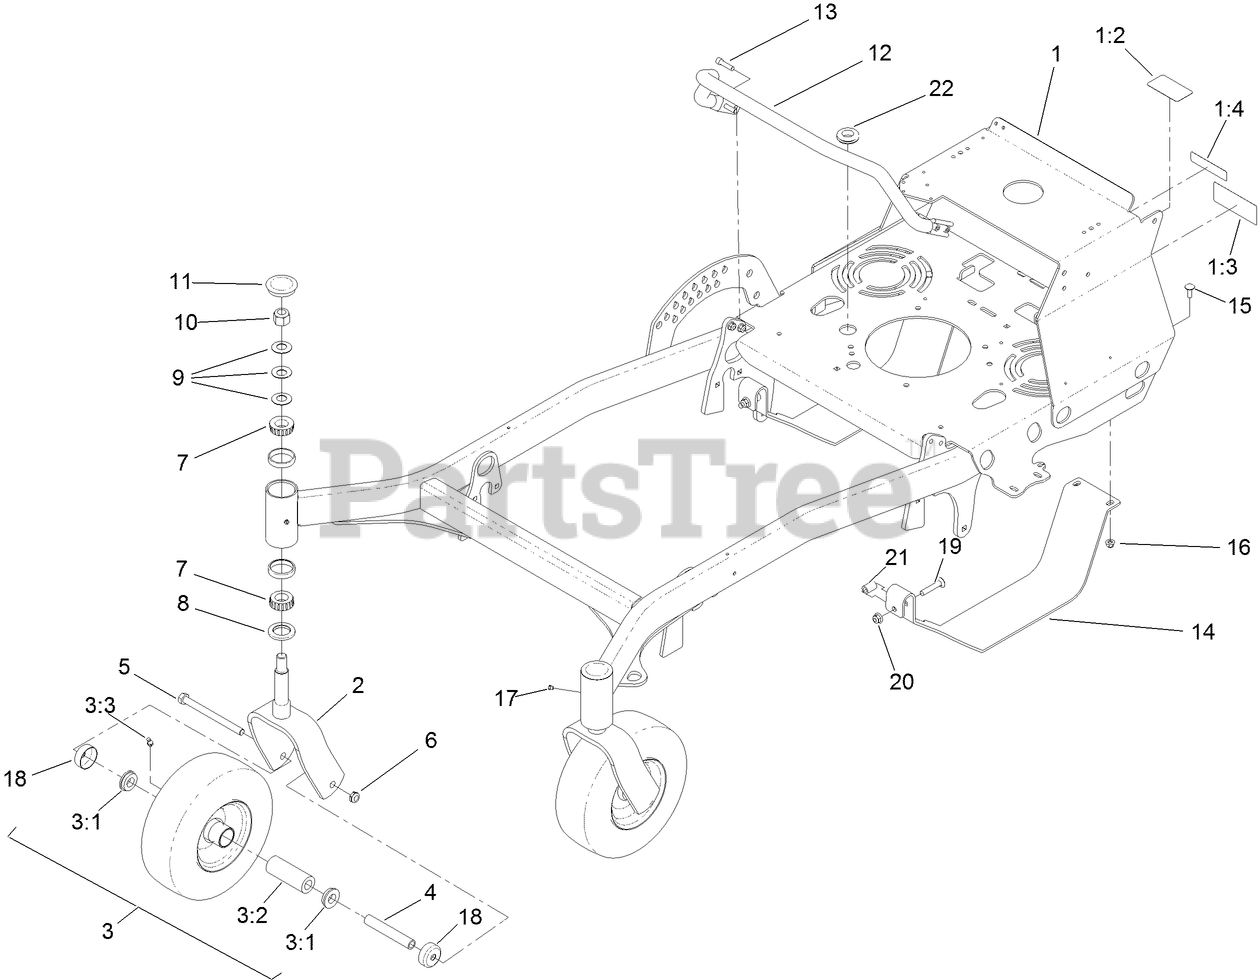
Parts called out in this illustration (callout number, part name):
1	FRAME ASM
1:2	DECAL - BYPASS
1:3	DECAL-WARNING, SULKY
1:4	DECAL-WARNING
2	FORK-CASTER
3	WHEEL AND TIRE ASM
3:1	BUSHING
3:2	BEARING
3:3	FITTING-GREASE
4	SPACER
5	SCREW-HH
6	NUT-HEX
7	BEARING-ROLLER, TAPERED
8	SEAL-GREASE
9	WASHER-BELLVILLE
10	NUT-LOCK, NI
11	CAP-GREASE
12	TUBE, MUFFLER GUARD
13	SCREW-HSH
14	GUARD-TRANSMISSION
15	BOLT-CARR
16	NUT-HF, NI
18	GUARD-SEAL
19	BOLT-CARRIAGE
20	NUT-HF, NI
21	SPACER
22	GROMMET
